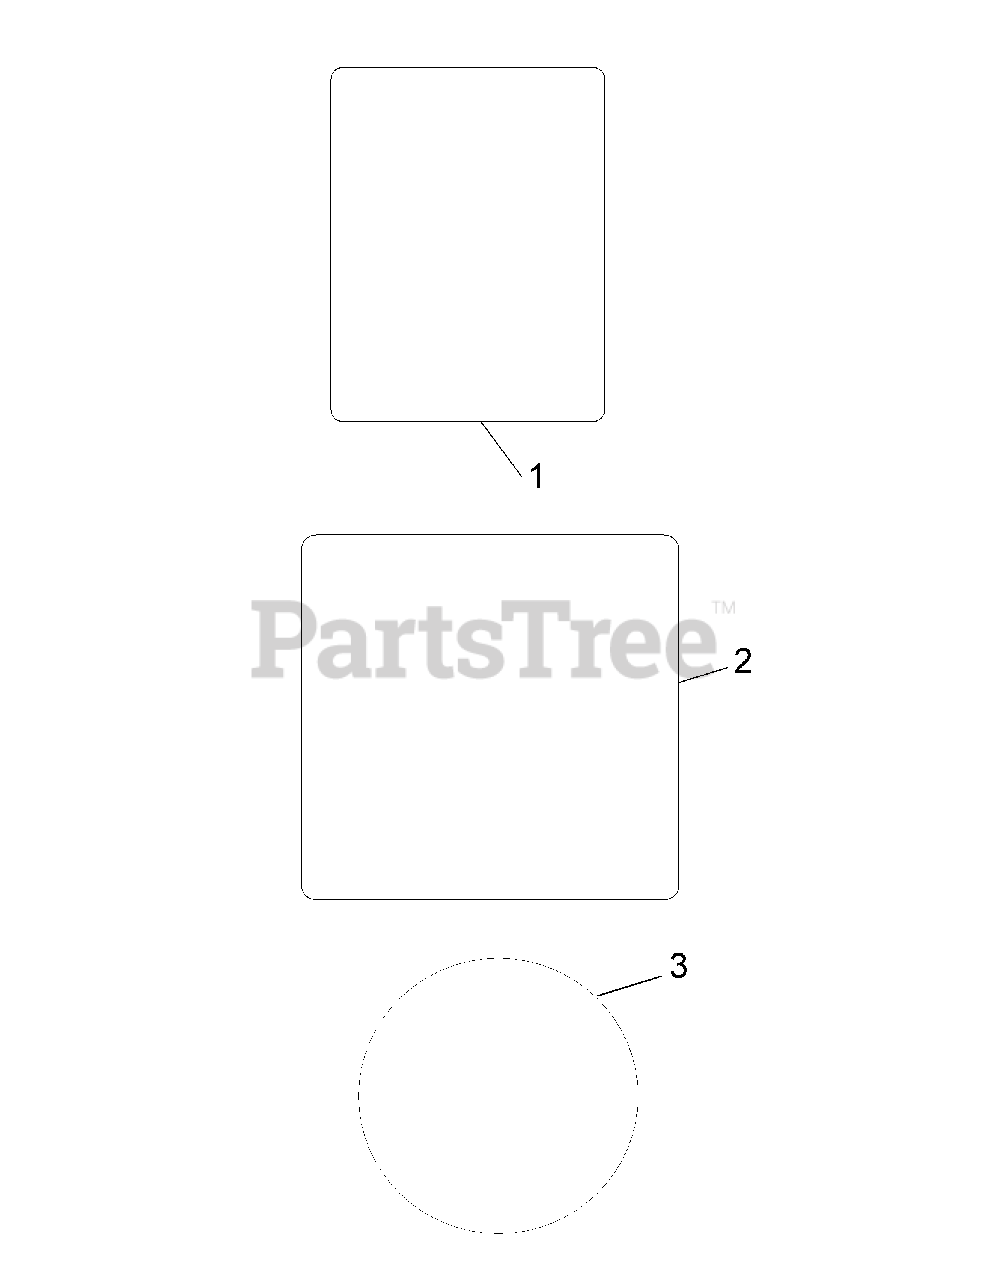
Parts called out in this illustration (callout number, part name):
1	Clear Laminate Decal
2	HDAC 747cc/CV-CH732 Decal
3	Grass Screen Decal
